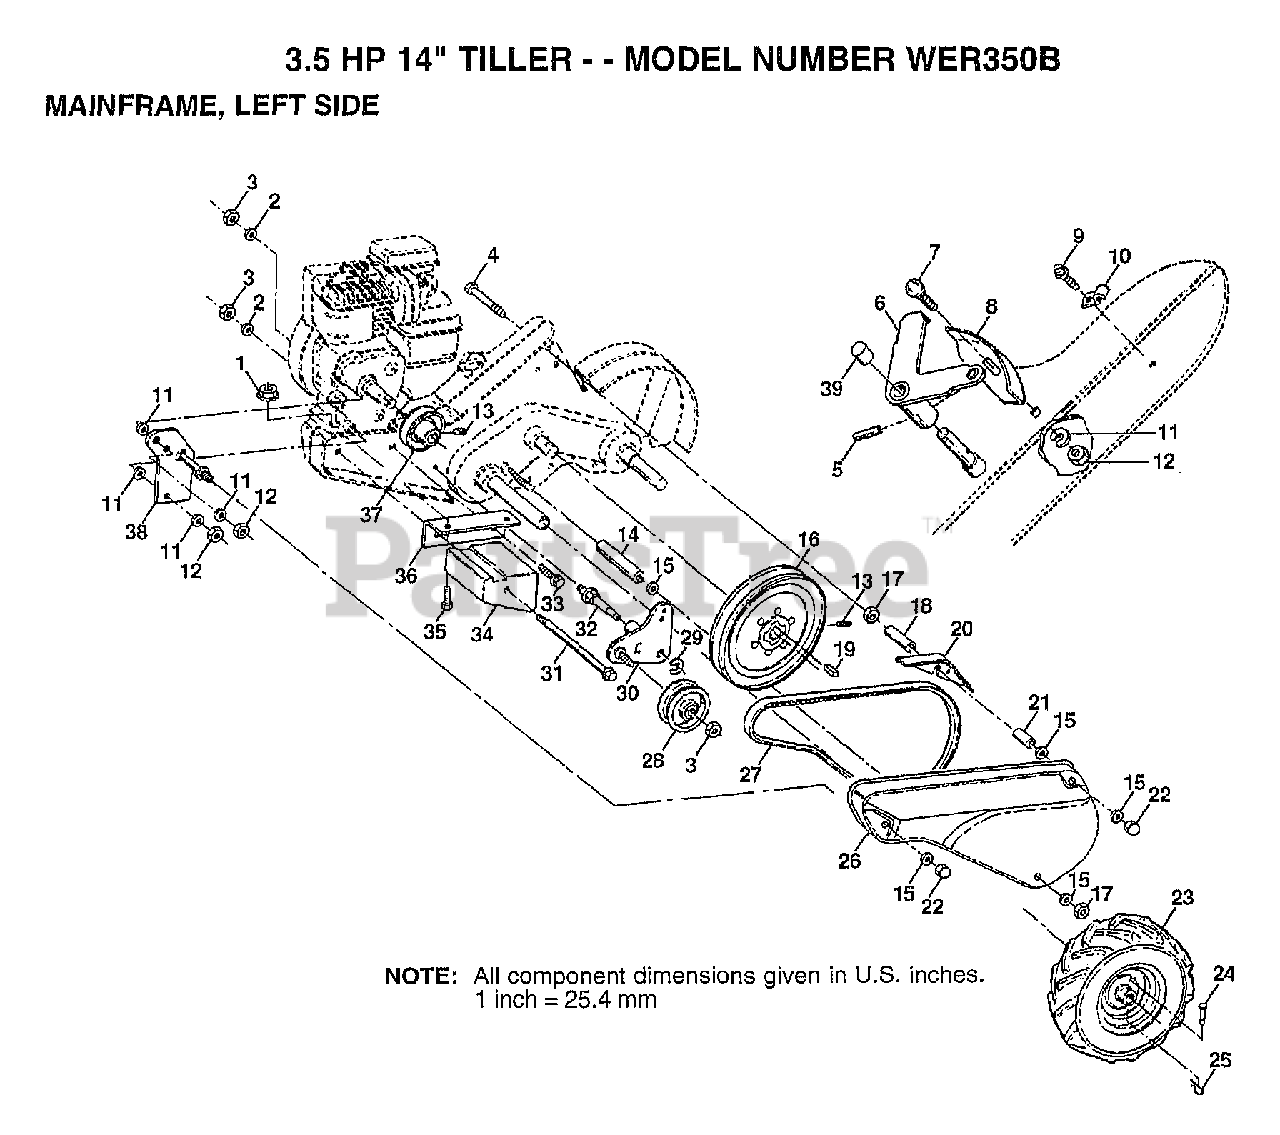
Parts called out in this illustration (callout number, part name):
2	LOCKWASHER
3	NUT.HEX.3/8-16UNC
4	BOLT TI
6	LEVER ASM CRT
7	BOLT
8	PANEL TI
10	CONDIUT CLIP T
11	LOCKWASHER
13	SET SCREW
14	SPACER
15	WASHER
16	"SHEAVE 10"" CRT"
17	NUT.HEX.5/16-18
18	SPACER CRT
19	KEY T
20	GUARD CRT
21	SPLIT SPACER
22	NUT TI
23	TIRE.CHV.13X5.0-6
23	RIM
24	RIVET.DRILL.1.75
25	RETAINER M
26	"GUARD, BELT"
27	BELT-V
28	PULLEY-IDLER TI
29	KLIP RING
31	BOLT CRT
32	SHIFT ARM CRT
33	BOLT
34	COUNTERWEIGHT CRT
35	BOLT.HEX.5/16-1.5
36	BRACKET LH CRT
37	ENGINE SHEAVE
38	BELT GUARD BRKT
39	CAP PLUNGER BLACK
